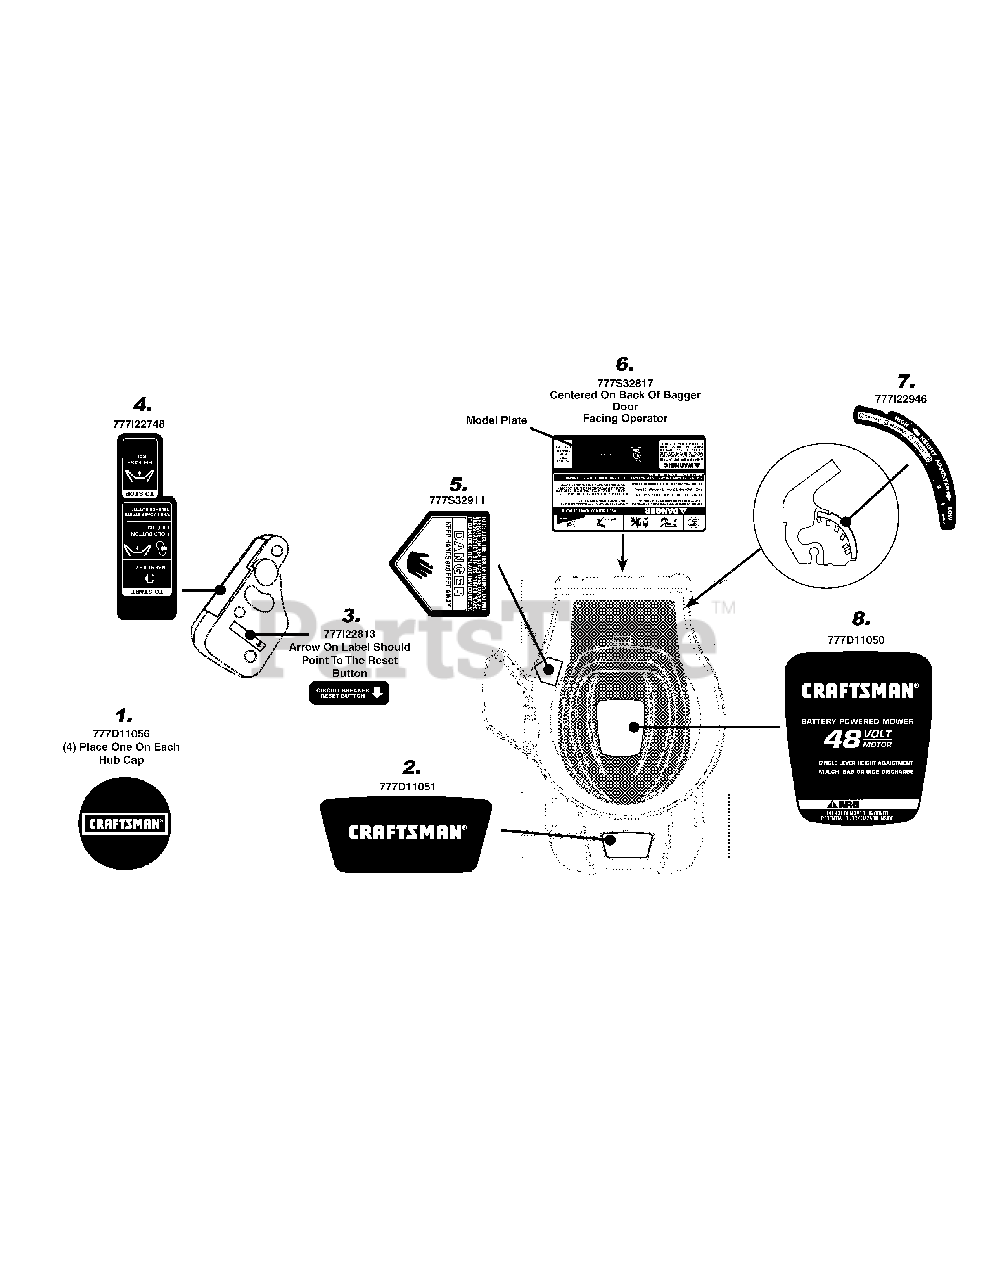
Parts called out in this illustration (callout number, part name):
1	LABEL-HUB CAP CRAFTSMAN
2	LABEL-MOWER FRT DR COVER CRFTSMN
3	LABEL-BREAKER RESET UL ELC/BAT MWR
4	LABEL-SWITCH START
5	LABEL-CUT FINGER
6	LABEL-REAR SAFETY
7	LABEL-MOWER HEIGHT ADJ
8	LABEL-MOWER BATTERY SHROUD CRFTSMN
